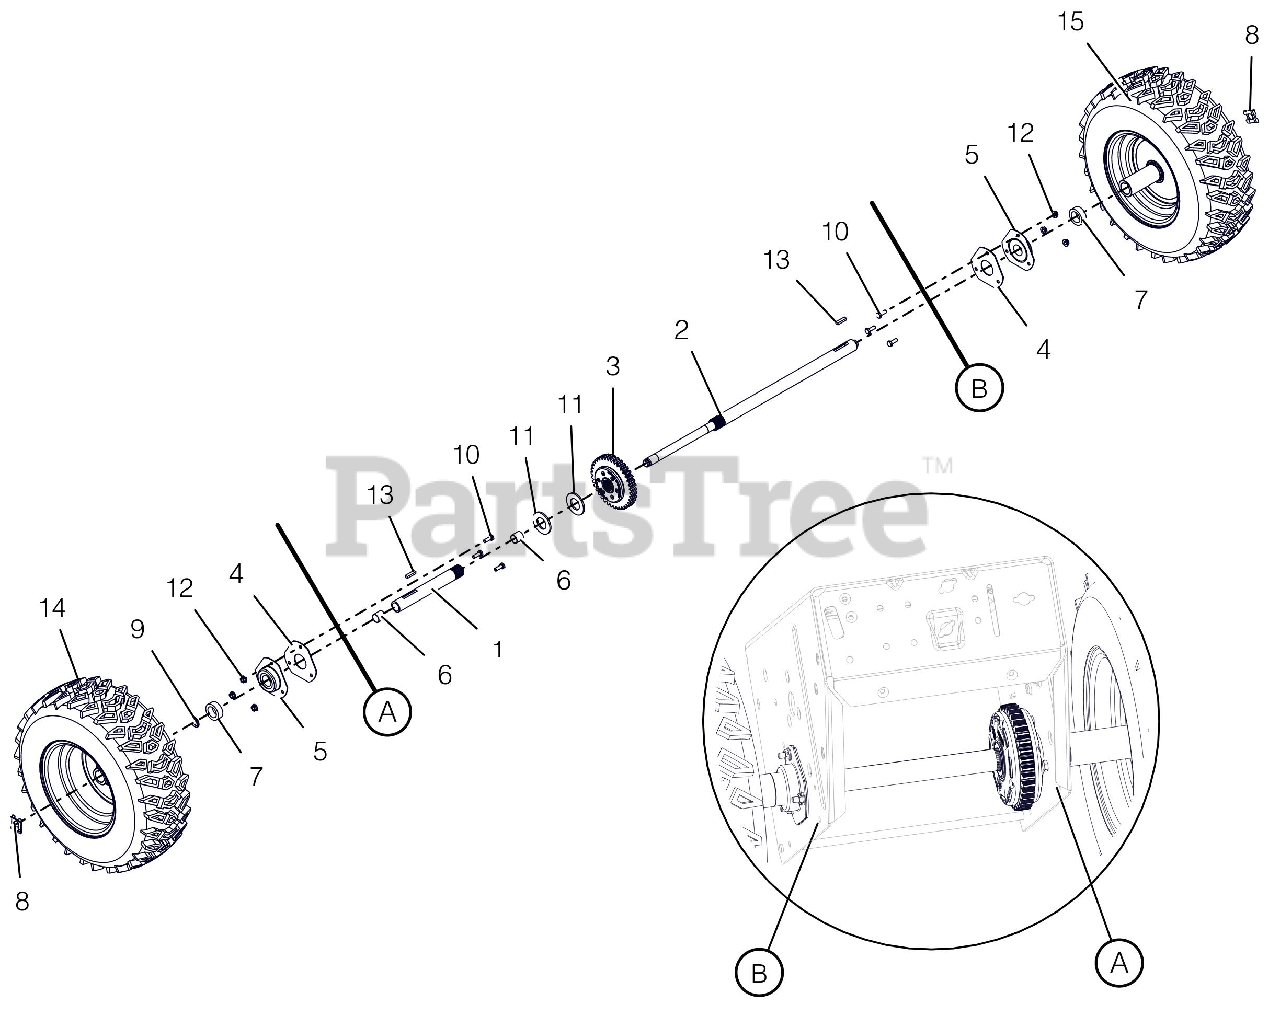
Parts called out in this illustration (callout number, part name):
1	AXLE, SHORT-AUTO W/BUSHINGS
2	AXLE, LONG-PRO AUTO DIFF
3	DIFFERENTIAL, AUTOMATIC
4	PLATE, BEARING SPACER
5	BRG-FLG 1.003/1.000 3 BOLT
6	BSHG-SLV .706X.764X.75 BRZ
7	SPACER, PRO AXLE BEARING
8	CLIP, SNAP .625 DIA
9	RG-RTNG-EXT .625X.042
10	@BLT-HEX .25-20X.75 GR5 YWZC
11	WSHR-FL-STL- 1.062X2.0X.134 YZ
12	@NUT-LK-CTR-FLG .25-20 YWZC
13	KEY-RECT .25X.188X1.00
14	TIRE/WHEEL,RH 16X6.5-8 DIFF T2
15	TIRE/WHEEL,LH 16X6.5-8 DIFF T2
